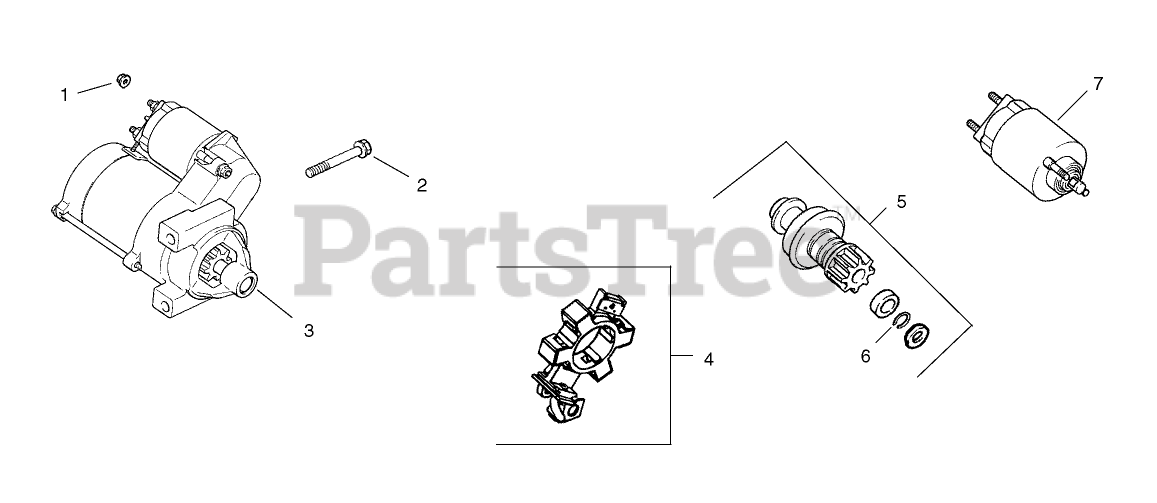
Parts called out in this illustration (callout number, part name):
1	NUT-FLANGE (M8X1.25)
2	SCREW-FLG (M8X1.25X80)
3	Starter assembly (Includes 4-7)
4	BRUSH HOLDER KIT
5	Kit, pinion drive (Includes 6)
6	RING-RETAINING
7	Solenoid Kit
